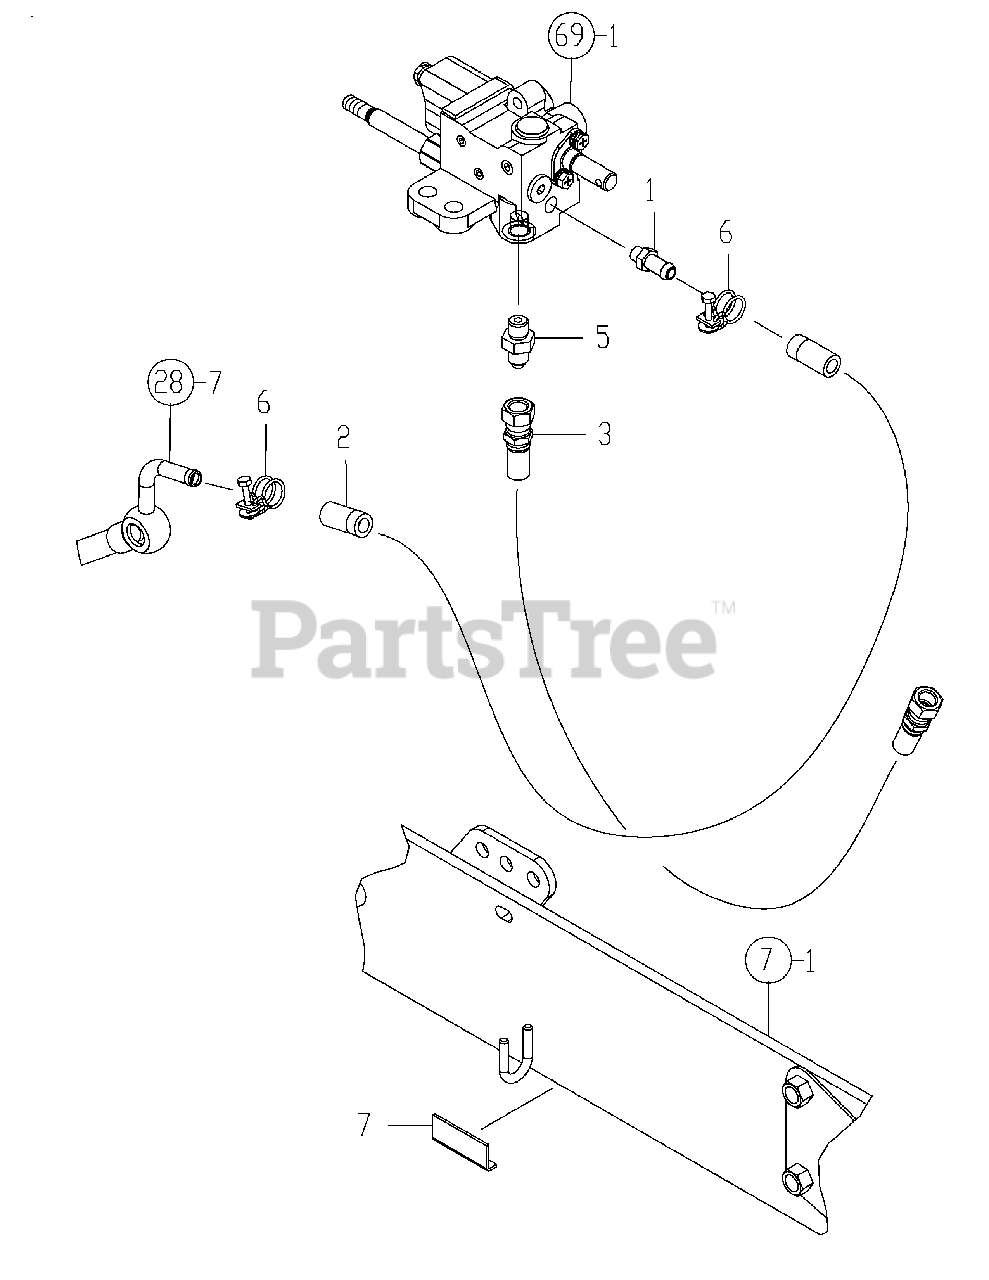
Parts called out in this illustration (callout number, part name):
2	LP HOSE, DRAIN
3	HP HOSE, CYLINDER
5	CONNECTOR PF1/4
6	CLAMP, HOSE 19
